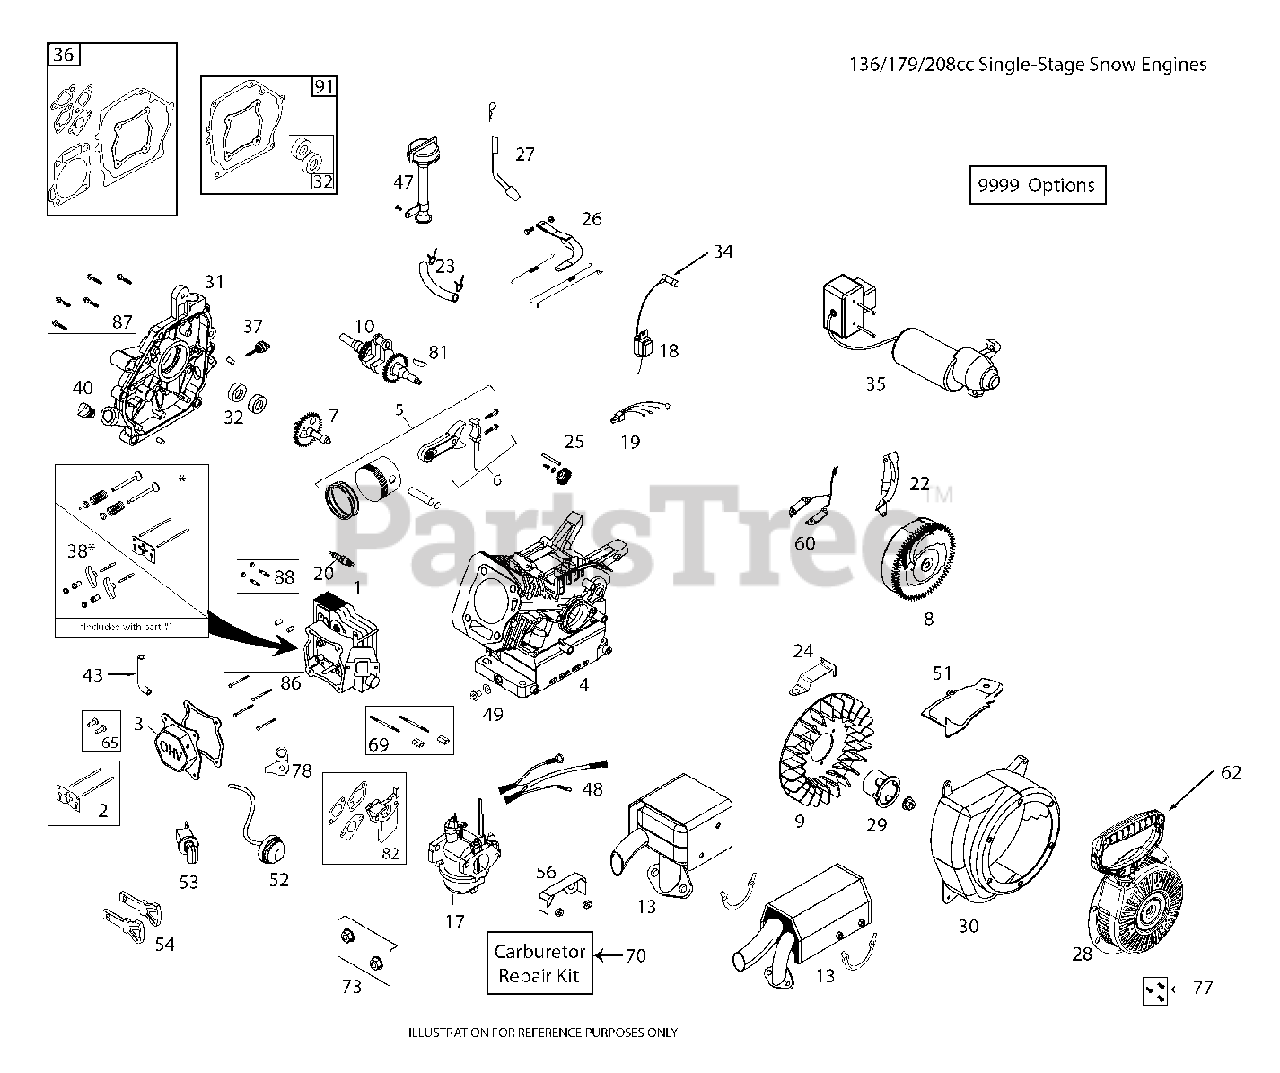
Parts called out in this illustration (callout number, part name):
1	CYLINDR.HEAD.SRV.KIT
2	KIT.PUSH.ROD.SRV(SK208-1001)
3	VALVE COVER ASSEMBLY
4	CYLINDER.ASM.SKSN0001.2
5	KIT.PISTON.SRV(SK208-1400)
6	KIT.CONNECT.ROD.SRV(SK208-1500
7	KIT.CAMSHAFT.208CC.LCT
8	FLYWHL.ASSY.ELECT.(SKSN0405)
9	KIT.COOLNG.FAN.SERV(SK208-4000
10	CRNKSHFT-KYD#14.208CCSKSNO8001
13	MUFFLER.ASM.LCT.208CC.SNGL.STG
17	CARB.ASM.SS/SNO.LCT(SKSNO313)
18	IGNITION COIL LCT.SKSN0418.1
19	Husqvarna TBD
20	SPARK.PLUG(2083810)
22	SHLD.ELEC.START.FLY(SKSN-0605)
23	KIT.FUEL.HOSE.208CC.SING/STAGE
24	SPEED.CTRL.BRKT.(SKSN0150)
25	GOVENOR.GEARS ASM(SK2082900)
26	CARBURETTOR GOVERNOR LINK.ASM.
27	KIT.GOVERNOR.CRANK(SK208-3100)
28	STARTER.RECOIL.S/S SNO.78".ROP
29	STRTER.CUP(NON-SLOT)SKSN0601.2
30	BLOWER.HOUSING.ELEC.START.LCT
31	CRANKCASE COVER ASSY
32	SEAL KIT (2 PCS)
34	SPARK.PLUG.BOOT.SNW,SKSN4691.1
35	STARTER STARTER.EURO
36	GASKET.KIT.208CC(SK2084300.1)
37	DIPSTICK SMALL
38	ROCKER ARM KIT
40	NON REMOVABLE PLUG
43	TUBE.BREATHER.LCT.208
47	HIGH OIL-FILL TUBE ASSY
48	HARNESS.WIRE/WCDI.IGN.LCT
49	KIT.OIL.DRAIN.PLUG(SK2089911
51	SHIELD.CYLINGER.LCT.SKSN0608.1
52	BULB.FUEL.PRMR.W/HOSE(SKSNO306
53	SWITH.KEY.ASSEM.SNOW.SINGLE.ST
54	KEY SET(2 KEYS) SKSN0407.1
56	SHIELD.VAPOR.SNOW
60	Husqvarna TBD
62	STARTER.GRIP.SNOW.LCT.SKSN0603
65	TAPPET.KIT.LCT.208CC
69	CARB.STUDS & COUPLING KIT.SNOW
70	CARB.REPAIR.KIT.LCT.SK9900.2
73	SHIELD.INTAKE.(LCT.SKSN0140.1)
77	BOLT.KIT.RECOIL.LCT.ALL.ENGINE
81	KEYS.FLYWHEEL.208/414CC.5PACK
82	SPACER.CARBURETOR.208CC.LCT
86	KIT.BOLT.CYLINDER.HEAD.(4PC)
87	KIT.BOLT.CRANKCASE.COVER.6PC
88	STUD.MUFFLER.KIT.LCT
91	COVER CRANKCASE GASKET
9999	HIGH.ALTITUDE.JET.(>6,000FT)
